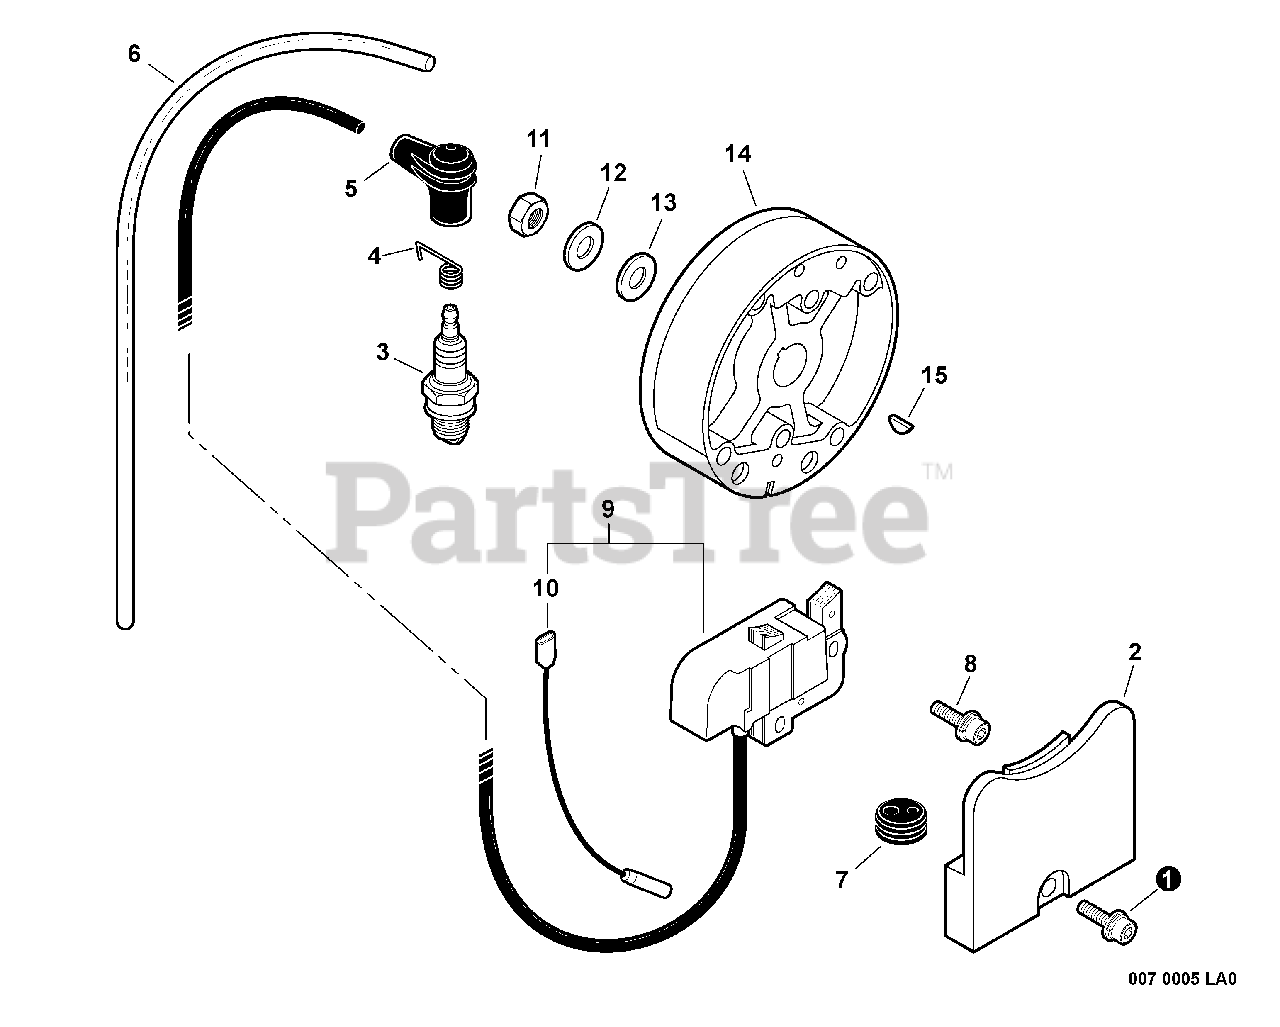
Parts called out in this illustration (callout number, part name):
1	BOLT 5×22
2	COVER, DUST
3	SPARK PLUG - BPM8Y
4	TERMINAL, SPARK PLUG
5	CAP, SPARK PLUG
6	TUBE, VINYL 6.3×8×380
8	BOLT 5×22
9	COIL ASSY, IGNITION
10	LEAD - IGNITION
12	WASHER, SPRING 10
13	WASHER, SPRING 10
14	FLYWHEEL
15	KEY, WOODRUFF 3×14
